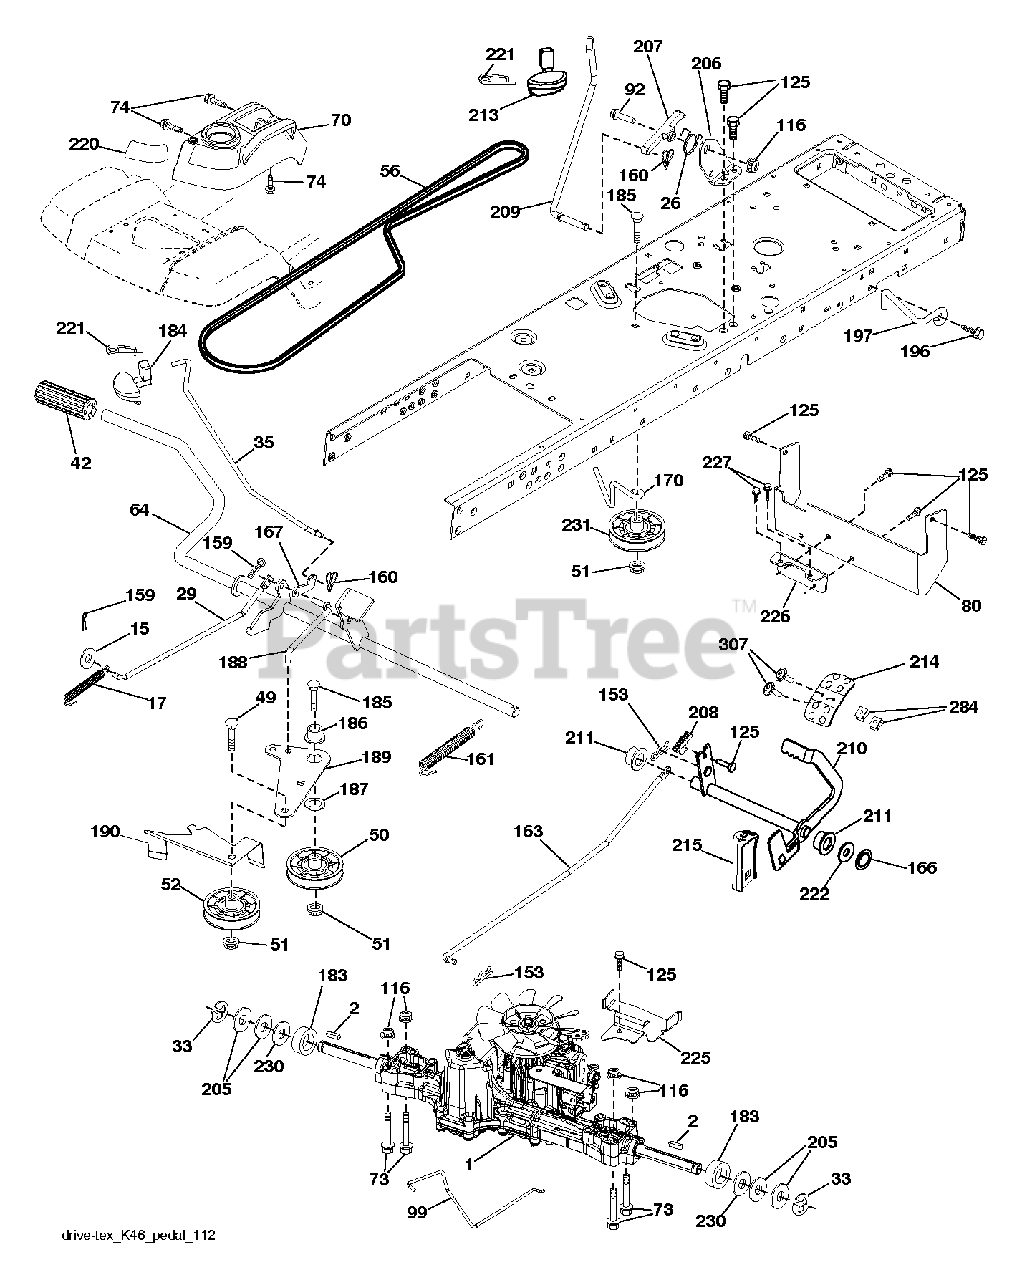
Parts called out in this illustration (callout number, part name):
2	SQUARE KEY
15	WASHER
17	SPRING.BRAKE.K46.GREEN
26	SPRING.RETURN.CRUISE
29	ROD.BRAKE.K46
35	ROD.BRAKE.PARTK.HUSQ.TEX
42	PEDAL COVER T
50	IDLER.FLAT.910.OFFSET
51	NUT LOCK FLG 3/8-16 UNC
52	IDLER.V-GROOVE.910.OFFSET
56	V-BELT.MOWER.92.40.42/K46
64	SHAFT.ASM.PEDAL.BRK.CNTR
70	CONSOLE.ASM.RH.GT.FC.HUSQ
74	SCREW.HI-LO.CONSOLE
80	STRAP.TORQUE.K46.K57R.TT
92	BOLT
99	ROD.SPRING.BYPASS.K46.LT.Z
116	NUT LOCK HEX FLANGE 5/16-18
125	SCREW
153	RETAINER M
159	COTTER PIN
160	RETAINER CLIP
161	SPRING, RETURN LT
163	ROD.CONTROL.K57R.K46
166	NUT.PUSH.625
167	LATCH.BRAKE.SPRING
170	KEEPER.CENTER SPAN.1.688
183	SPACER AXLE
184	RB HANDLE.PARKG.BRK.HUS/PRED
186	SPACER.RETAINER
187	WASHER 12/32X2X10GA
188	RP LINK.CLUTCH.GROUND.DRIVE
189	BELLCRANK.GROUND.DRIVE.TEX.
190	KEEPER.BELLCRANK.DRIVE
196	SCREW 3/8-16X1
197	LINK.CLUTCH.ANIT-ROTAT
206	BRKT.MOUNT.LATCH.CRUIS
207	LATCH.CONTROL.CRUISE
208	GEAR.SECTOR.CONTROL.CR
209	ROD.CONTROL.CRUISE.GT.
210	ROCKER.ASM.PEDAL.CONTR
211	BEARING.NYLON
213	KNOB.CONTROL.CRUSIE.HU
214	PEDAL.FORWARD.HUSQVARNA.DEALER
215	PEDAL.REVERSE.TEX.GT.4
220	REFLECTOR.RH.TEX GT
221	RETAINER.SPRING.CLIP.H
222	WASHER 21/32 X 1-1/4 X 10 GA.
225	KEEPER.BELT.TRANSAXLE.K46
226	BRACKET.MOUNT.TORQUE.K46.TLT
227	SCREW
230	WASHER.HARDENED
231	IDLER.V-GROOVE.1.688.OFFSET
284	NUT.U-CHNL.1/4-20.550DP.350PNL
307	SCREW.MACHINE.CR.1/4-20
